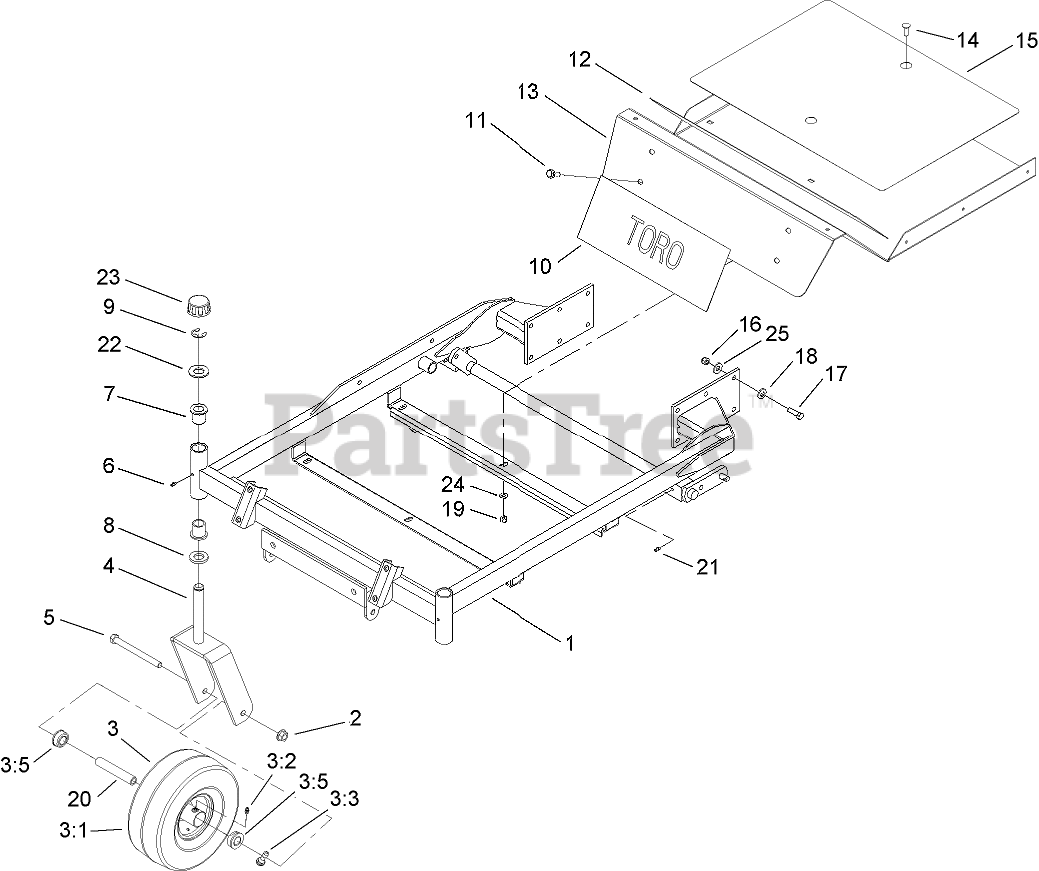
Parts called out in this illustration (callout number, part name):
1	CARRIER FRAME ASM
2	NUT-HF
3	FRONT WHEEL AND TIRE ASM
3:2	FITTING-GREASE
3:3	STEM-VALVE
3:5	BUSHING-FLANGE
4	CASTER FORK ASM
5	SCREW-HH
6	FITTING-GREASE
7	BEARING-FLANGED
8	WASHER-FLAT
9	RING-RETAINING, EXT
10	DECAL
11	SCREW-HHF
12	PAD-SKID, ANTI
13	FLOORPAN
14	SCREW-CARR
15	PAD-SKID, ANTI
16	NUT-LOCK, NI
17	SCREW-HH
18	WASHER-BELLEVILLE
19	NUT-LOCK, NI
20	BUSHING-SPANNER
21	FITTING-GREASE
22	WASHER
23	CAP-HUB
24	WASHER-PLAIN
25	WASHER-HARDENED
